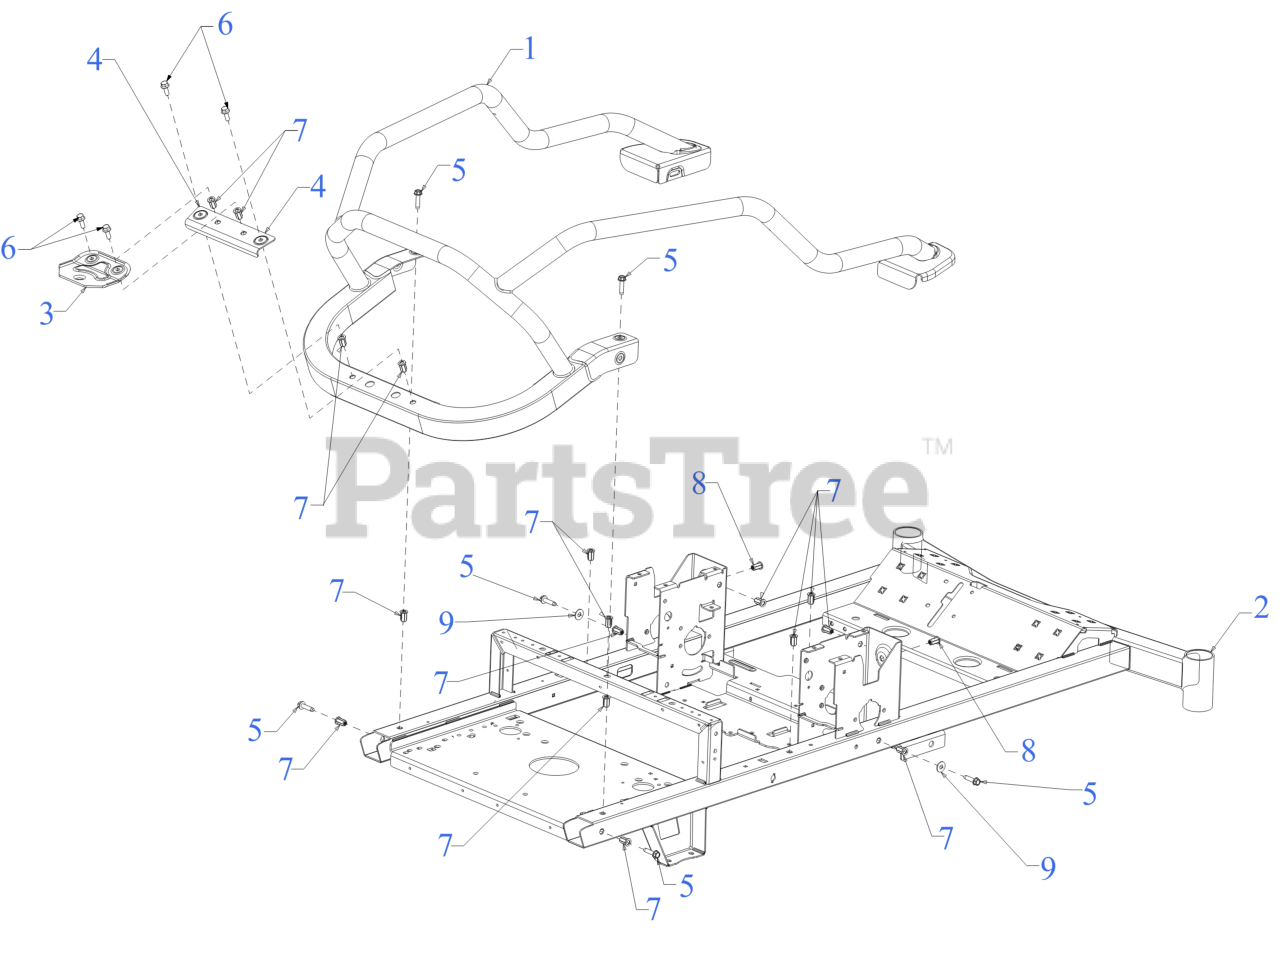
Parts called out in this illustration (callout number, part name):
1	UPPER FRAME
2	FRAME (LOWER)
3	HITCH PLATE
4	HITCH MOUNT
5	SCREW 5/16-18 x 1.25
6	SCREW 5/16-18 x .875 GR5 HXFLG HD
7	NUT RIVET 5/16-18
8	NUT RIVET 5/16-18
9	FLAT WASHER
